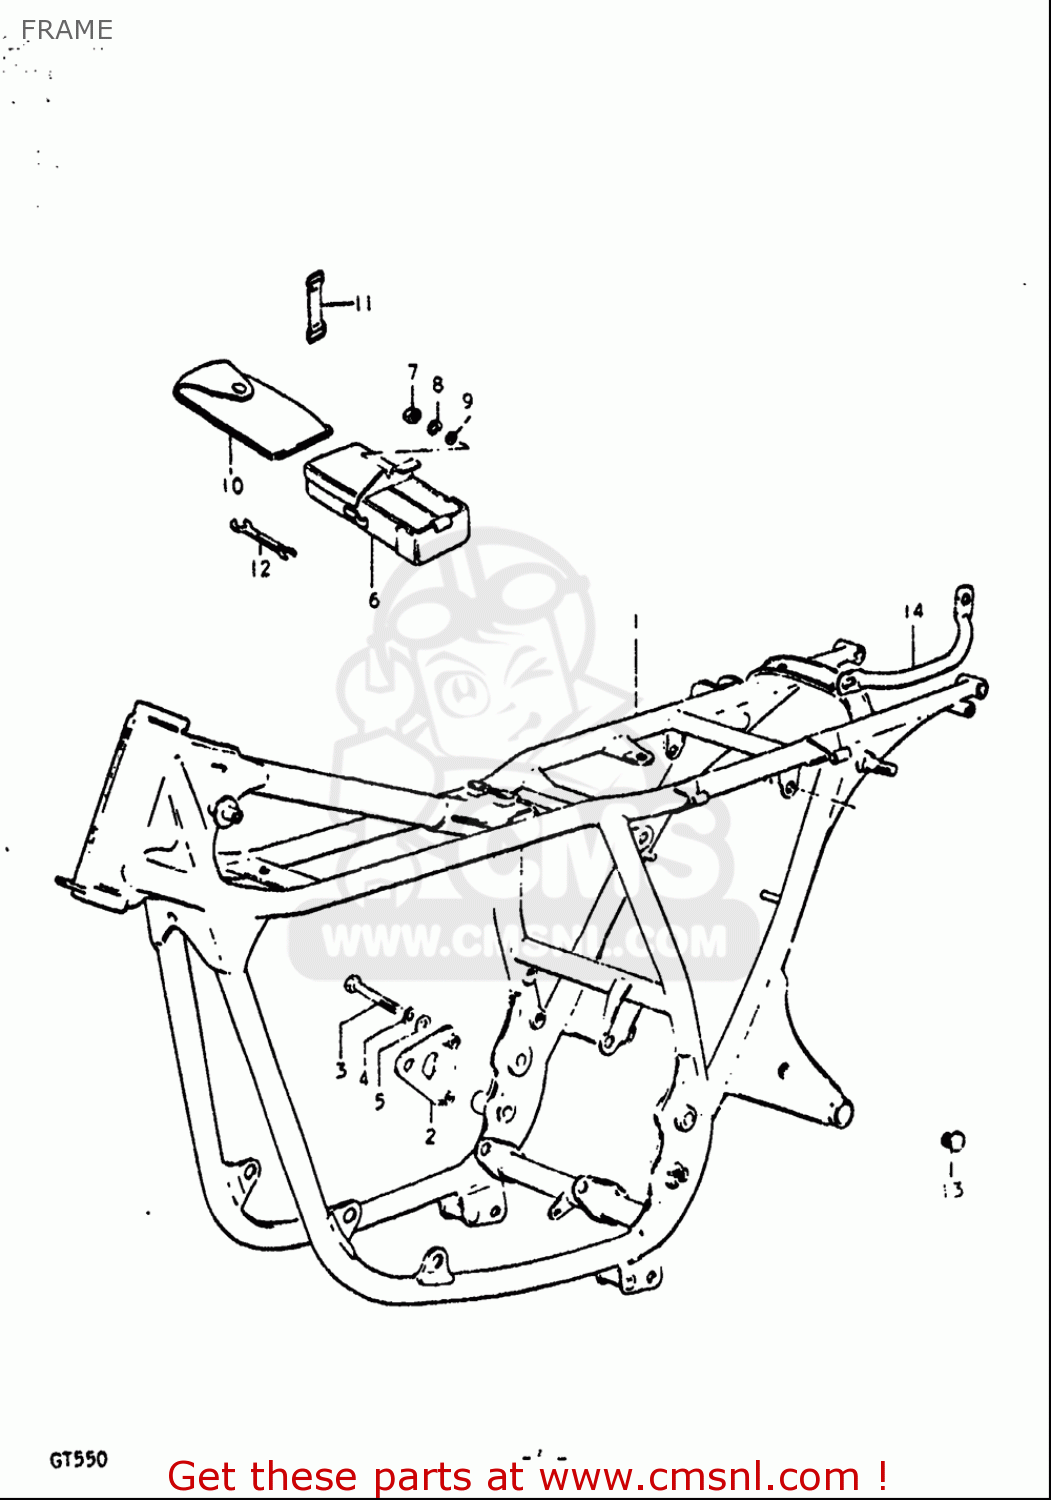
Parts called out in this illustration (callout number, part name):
3	BOLT
4	WASHER,LOCK
5	WASHER
7	NUT
8	WASHER,LOCK
9	WASHER
10	TOOL ASSY
11	BAND
13	CAP(OD:14)
